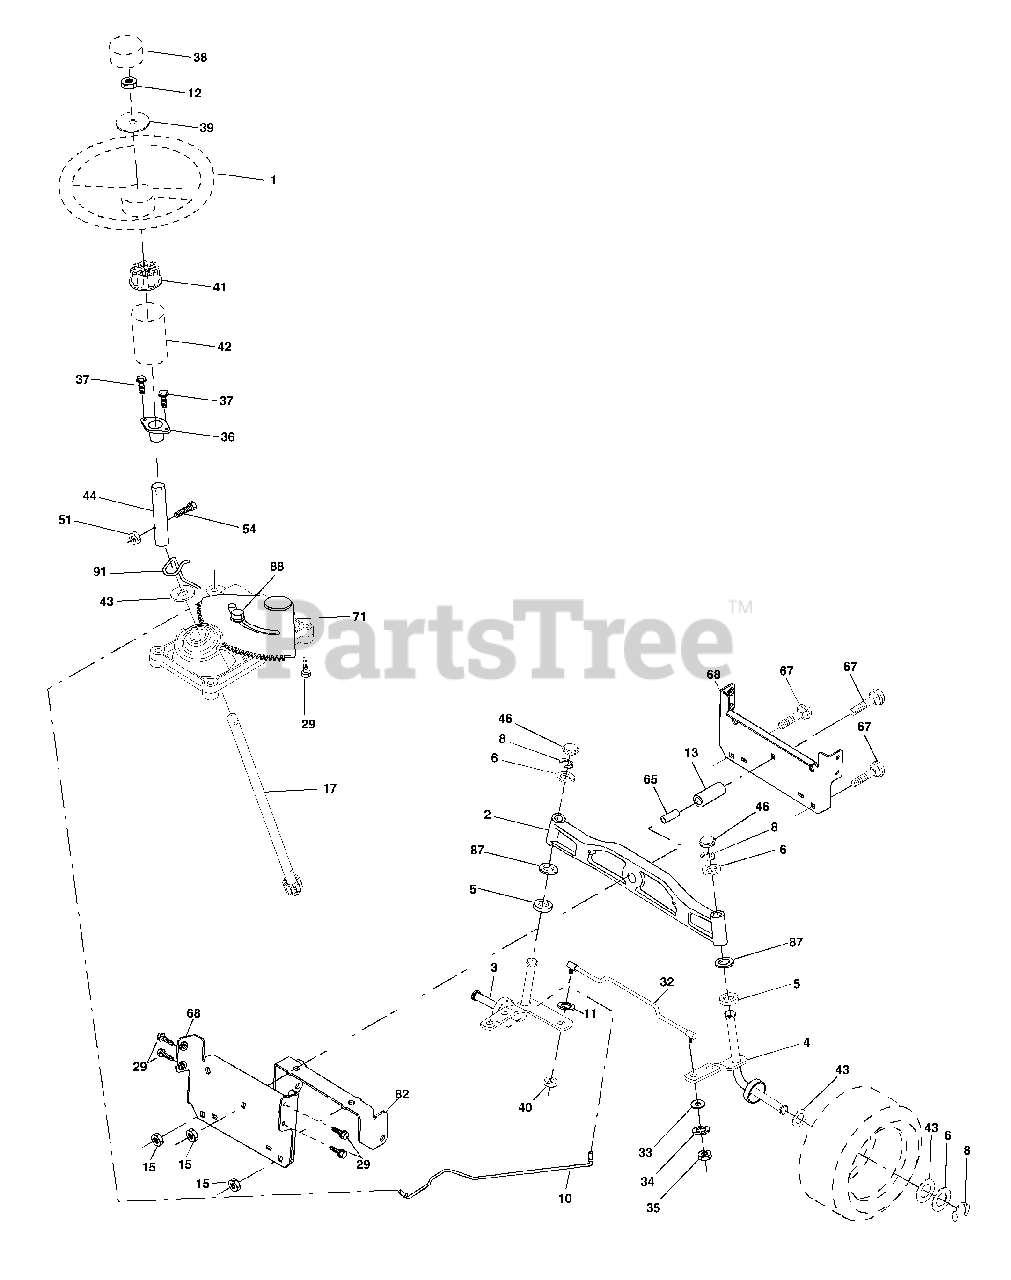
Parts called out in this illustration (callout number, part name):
1	Wheel Steering
2	Axle Cast Lt Machined
3	Spindle Asm LH
4	Spindle Asm RH
5	Bearing Race Thrust Harden
6	Washer 25/32 X 1-5/8 X 16 Ga
8	Ring Klip #t5304-75
11	Washer Lock Hvy Hlcl Spr 3/8
12	Nut Hex Jam Toplock 1/2-20 Unf
13	Spacer Brg Axle Front
15	Nut Hex Flange Lock
17	Shaft Asm Strg
29	Screw 3/8-16x3/4
32	Rod Tie Ball J
33	Washer 11/32 x 3/4 x 16 Ga.
34	Washer Lock Hvy Helical 5/16
35	Nut Crown Lock 5/16-24 Unf
36	Bushing Strg
38	Insert Cap Strg Wh
39	Washer 9/16 x 1-1/2
40	Lock nut
41	Adaptor Wheel Strg
42	Boot
43	Washer 25/32 X 1 1/4 X 16 Ga
44	Extension Steering Shaft LR/LT
46	Cap Spindle Fr Top Blk
51	Nut Crownlock 1/4-28
54	Bolt Hex 1/4-28 unf x 1-1/4 Gr. 8
65	Spacer Brace Axle
67	Bolt Rdhd Sq 3/8-16 x 2-1/4
68	Axle, Brace
71	Steering Asm
82	Bracket Susp Chassis Front
87	Washer Flat .781 x 1-1/2 x .14
88	Bolt Shoulder 7/16-20
91	Clip Steering
